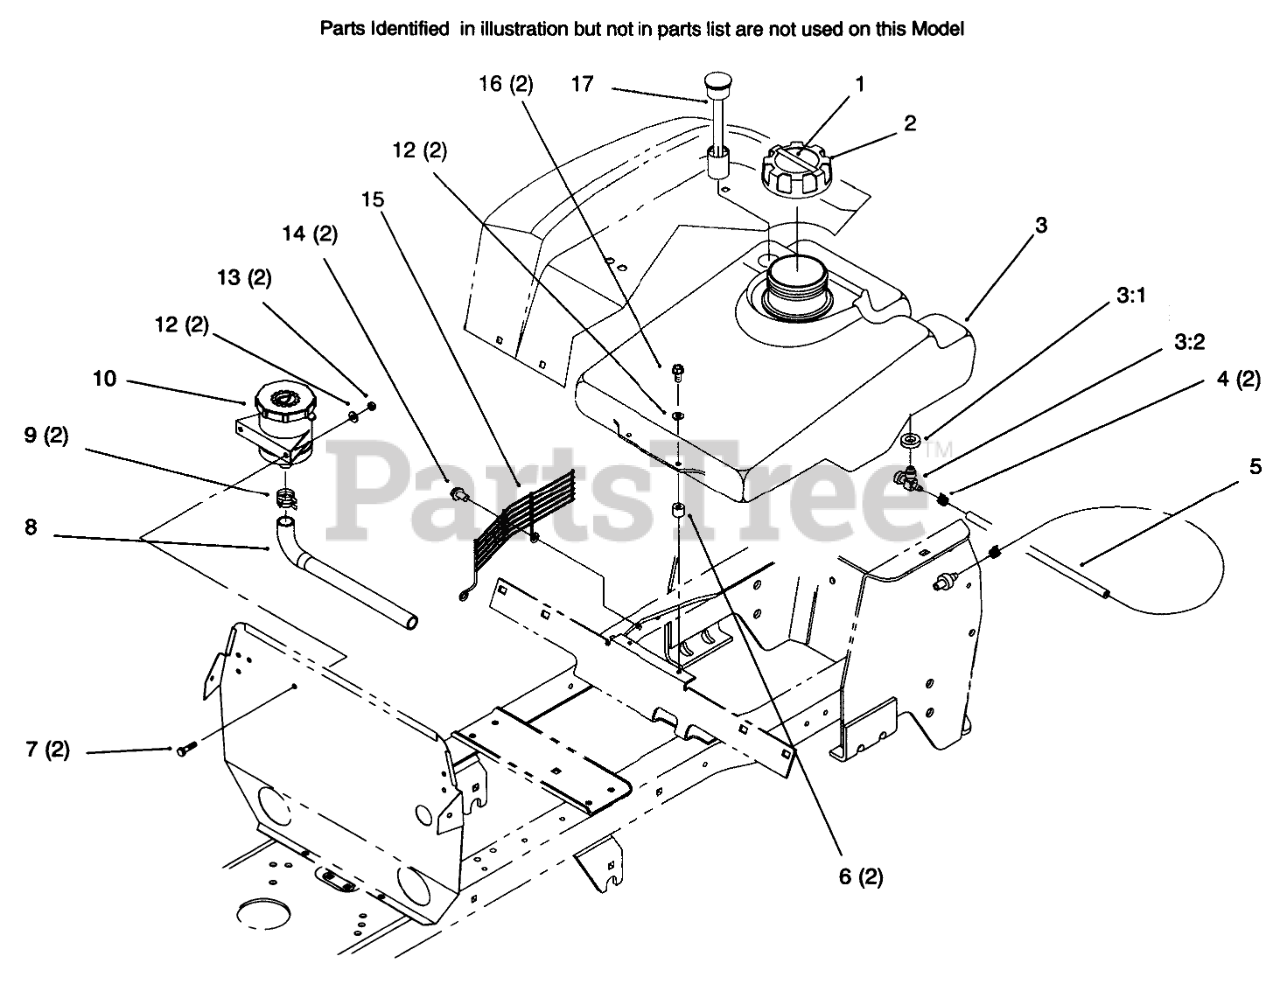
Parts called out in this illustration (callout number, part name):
2	GAS CAP ASM
3	Tank-Gas
3:1	VALVE-FUEL
3:2	BUSHING
4	CLAMP-HOSE
5	HOSE - FUEL LINE
16	SCREW-HWH
